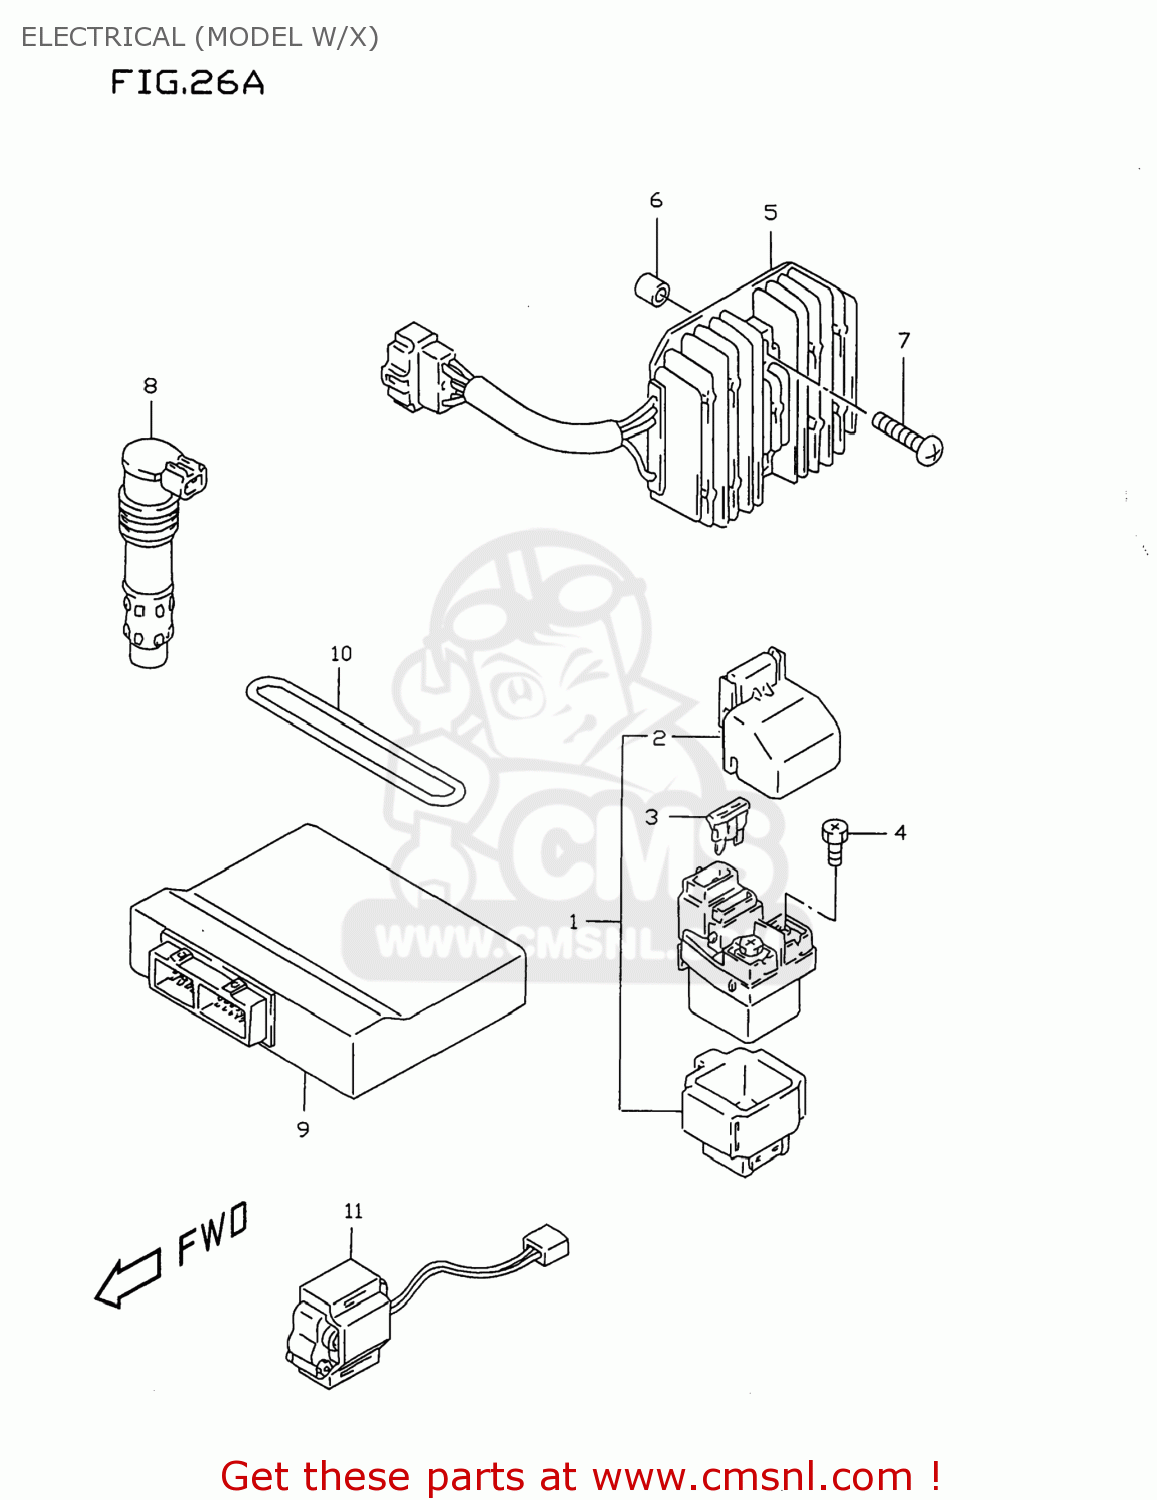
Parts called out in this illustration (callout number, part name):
1	RELAY ASSY,STARTING MOTOR
2	COVER,STARTER RELAY
3	FUSE(30A)
4	SCREW(6X8)
5	RECTIFIER ASSEMBLY
6	SPACER(6.5X10X7)
7	SCREW
8	COIL ASSY,IGNITION
9	CONTROL UNIT,EPI
10	BAND,BATTERY
11	SENSOR ASSY,FUEL CUT
